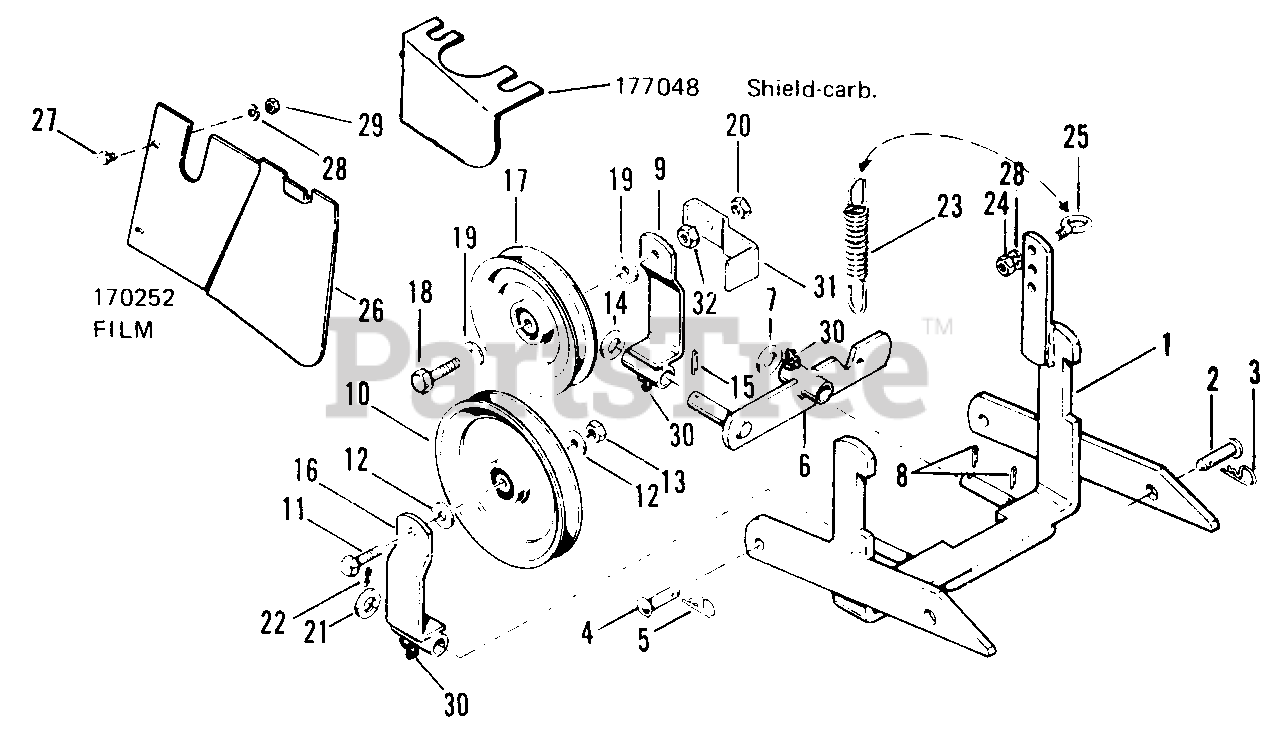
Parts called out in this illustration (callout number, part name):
1	Hitch Assembly
3	Spring Clip
5	Spring Clip
6	Idler Lever Assembly
8	Cotter Pin, 1/8" x 1"
9	Idler Bracket Assembly
10	Idler Pulley
11	Hex Capscrew, 3/8"-16 x 1-1/2"
12	Plain Washer, 3/8"
13	Hex Nut, Full, 3/8"-16
15	Cotter Pin, 1/8" x 1"
16	Idler Bracket Assembly
17	Idler Pulley
18	Hex Capscrew, 3/8"-16 x 1-1/2"
19	Plain Washer, 3/8"
20	Hex Nut, Full, 3/8"-16
22	Cotter Pin, 1/8" x 1"
24	Hex Nut, 1/4"-20
26	Deflector
27	Hex Capscrew 1/4"-20 x 1/2"
28	Lock Washer, 1/4"
29	Hex Nut, 1/4"-20
30	Grease Fitting
31	Belt Guide
32	Hex Nut, 3/8"-16
